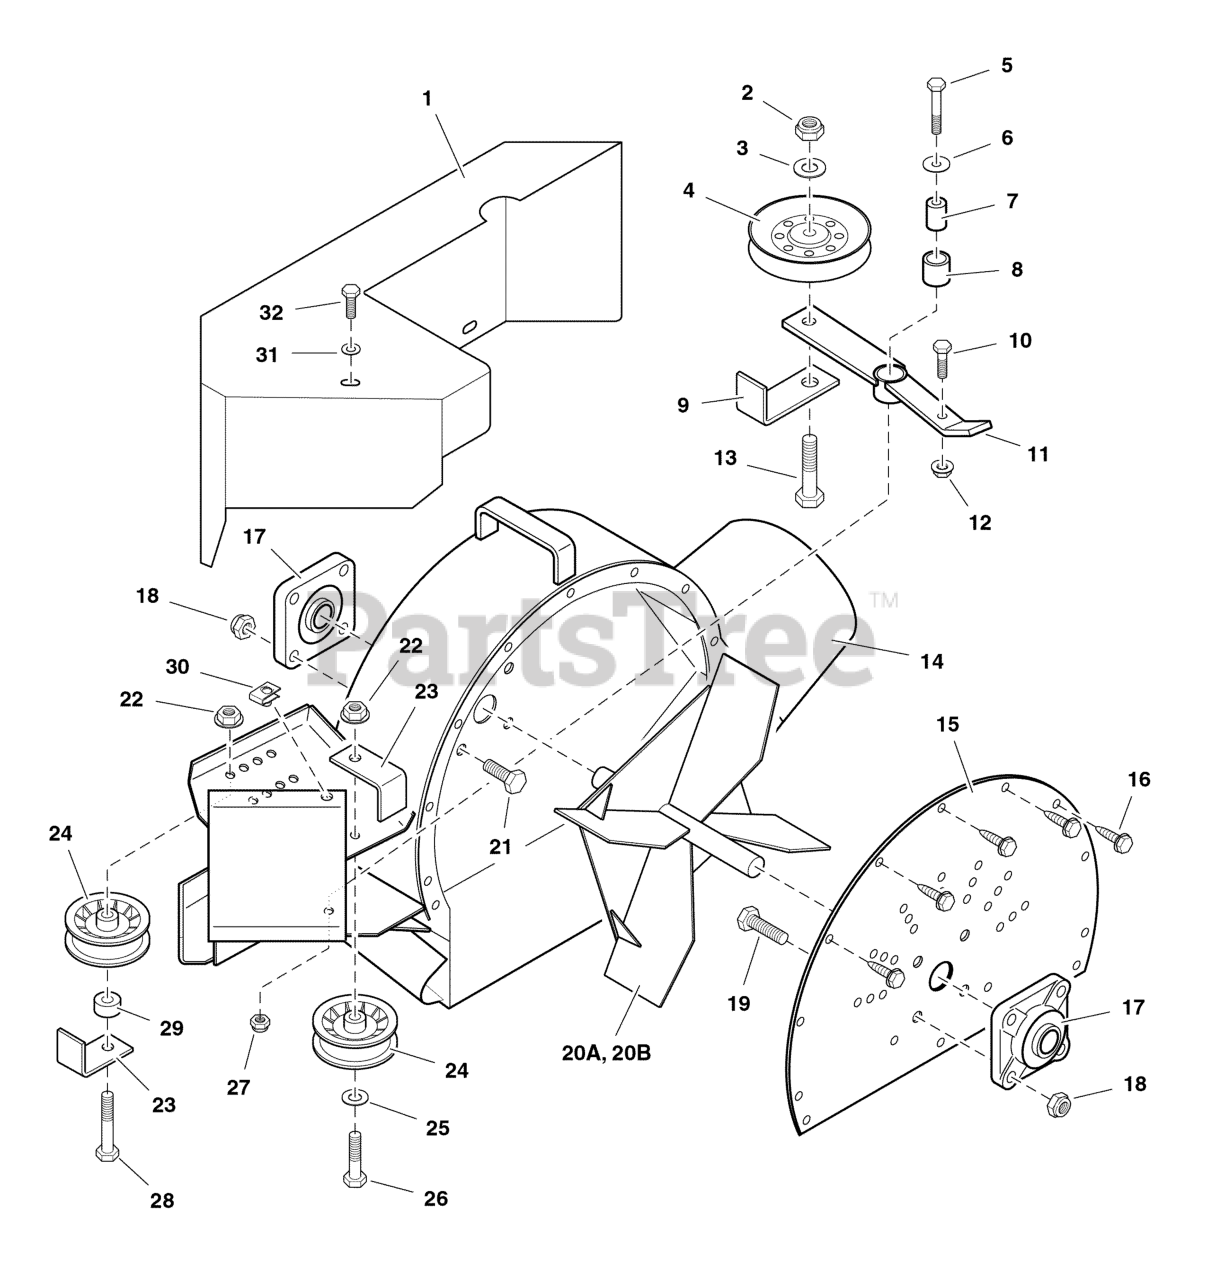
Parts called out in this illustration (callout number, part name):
1	BELT GUARD
2	NUT, 1/2-13 HEX NYLON LOCK
3	WASHER, 1/2 SAE
4	PULLEY, V-Idler
5	BOLT, 5/16-18 x 1-3/4
6	WASHER, 5/16" Fender
7	SPACER, .32 x .75 x 1.06
8	BUSHING, Brass
9	BELT KEEP
10	BOLT, 5/16-18 x 1-1/4
11	IDLER ARM
12	NUT, 5/16-18 HEX SERRATED FLANGE (SMALL)
13	BOLT, 1/2-13 X 2-1/4" GD5 CZ
14	BLOWER HOUSING
15	BACK PLATE
16	BOLT, Self-Tapping, 5/16-18 x 3/4
17	BEARING
18	NUT, 7/16-14 Hex Nylon Lock
19	BOLT, 7/16-14 x 1-1/2
20A	WELD, IMPELLER, FAST VAC BLOWER
20B	WELD, IMPELLER, FAST-VAC BLOWER
21	BOLT, 7/16-14 x 1-1/4
22	NUT, 3/8-16 Hex Serrated Flange
23	BELT KEEP
24	PULLEY, IDLER, 2.75"OD X .37"ID, INSERT
25	WASHER, 3/8 SAE
26	BOLT, 3/8-16 X 1-3/4" GD5 CZ
27	NUT, 5/16-18 Hex Nylon Lock
28	BOLT, 3/8-16 X 2-1/4" GD5 CZ
29	SPACER, .39 x 1.00 x .50
30	BODY CLIP, 5/16-18-7GA MATERIAL
31	WASHER, 5/16" SAE
32	BOLT, 5/16-18 X 1 GD5 YZ
